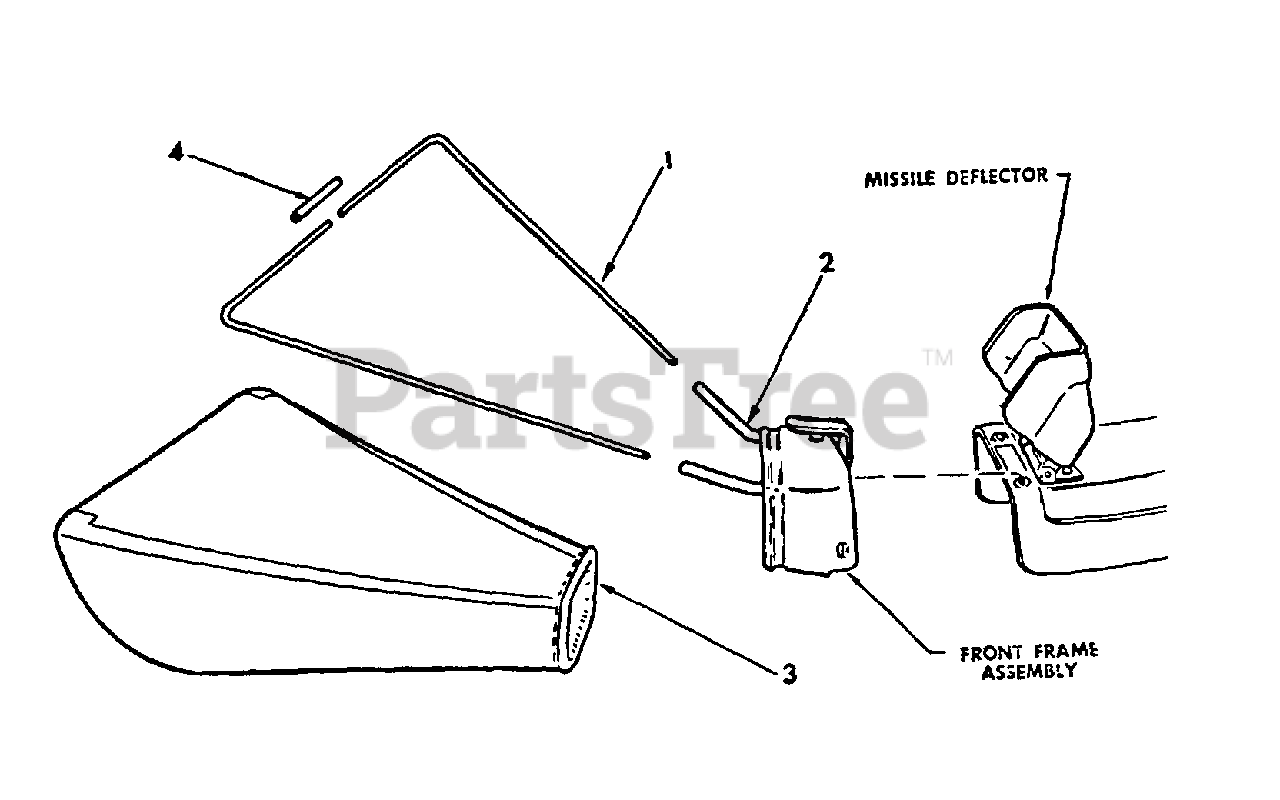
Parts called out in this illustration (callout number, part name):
1	SUPPORT, GRASS CATCHER
2	FRAME PKG, GRASS CATCHER
3	BAG, GRASS CATCHER
4	TUBE, FRAME COUPLER
